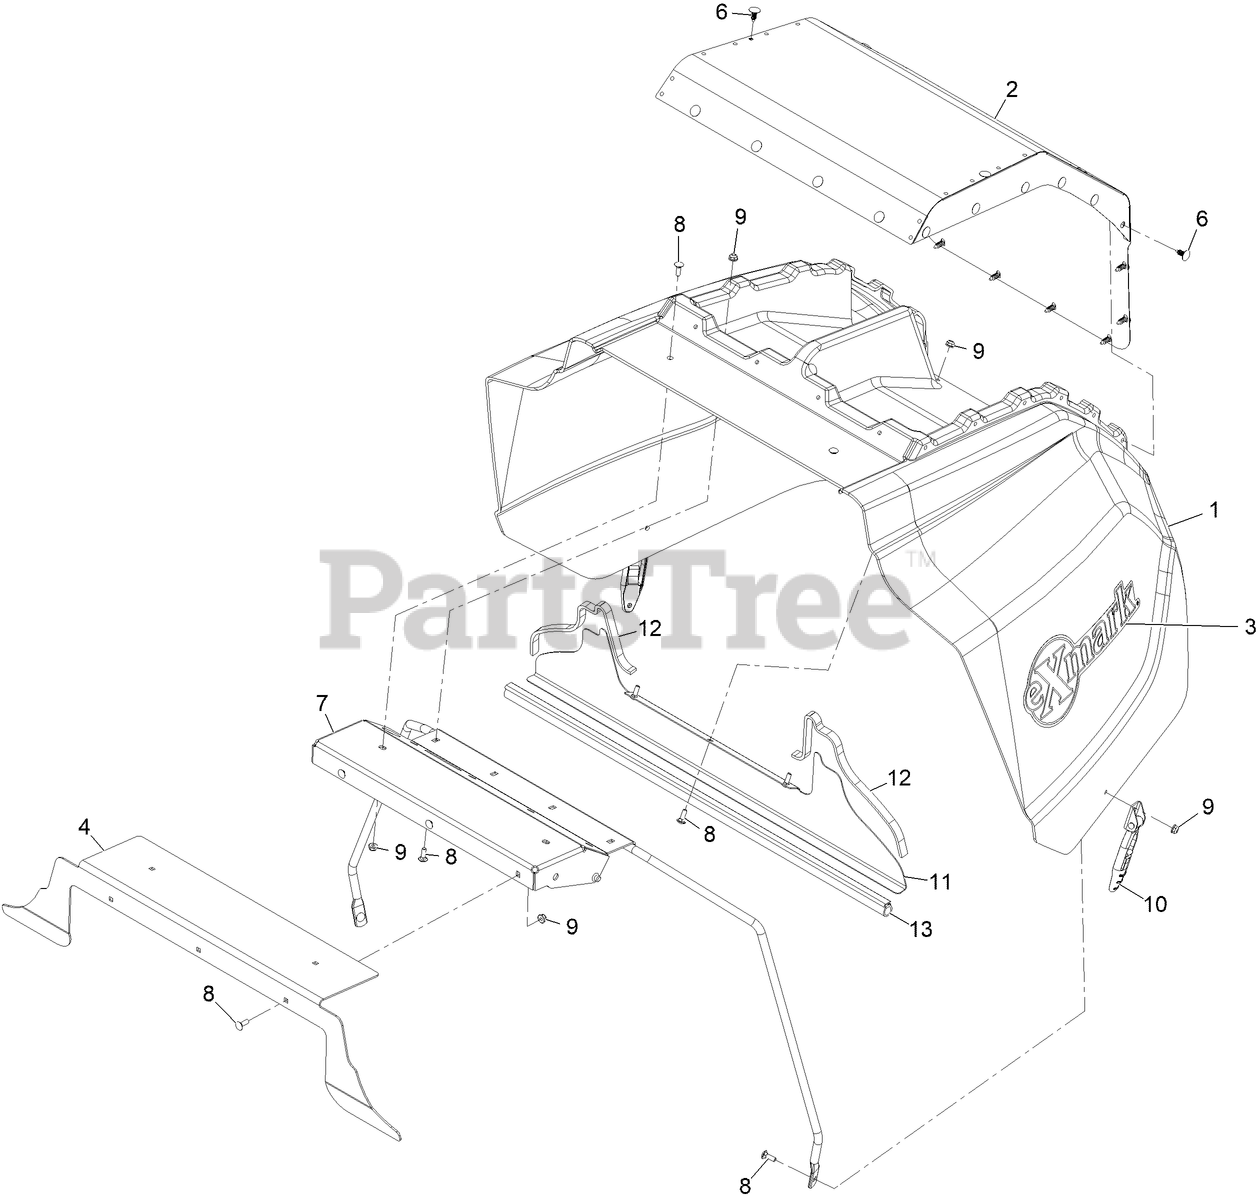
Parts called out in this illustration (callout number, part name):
1	HOOD,LZSD
2	Screen-Intake
3	DECAL-EXMARK
4	Block Off-Hood
6	PLUG-PLASTIC
7	SUPPORT-HOOD
8	BOLT-CARR
10	LATCH-RUBBER
11	Plate-Seal
12	SEAL-FOAM
13	Seal-Bulb
